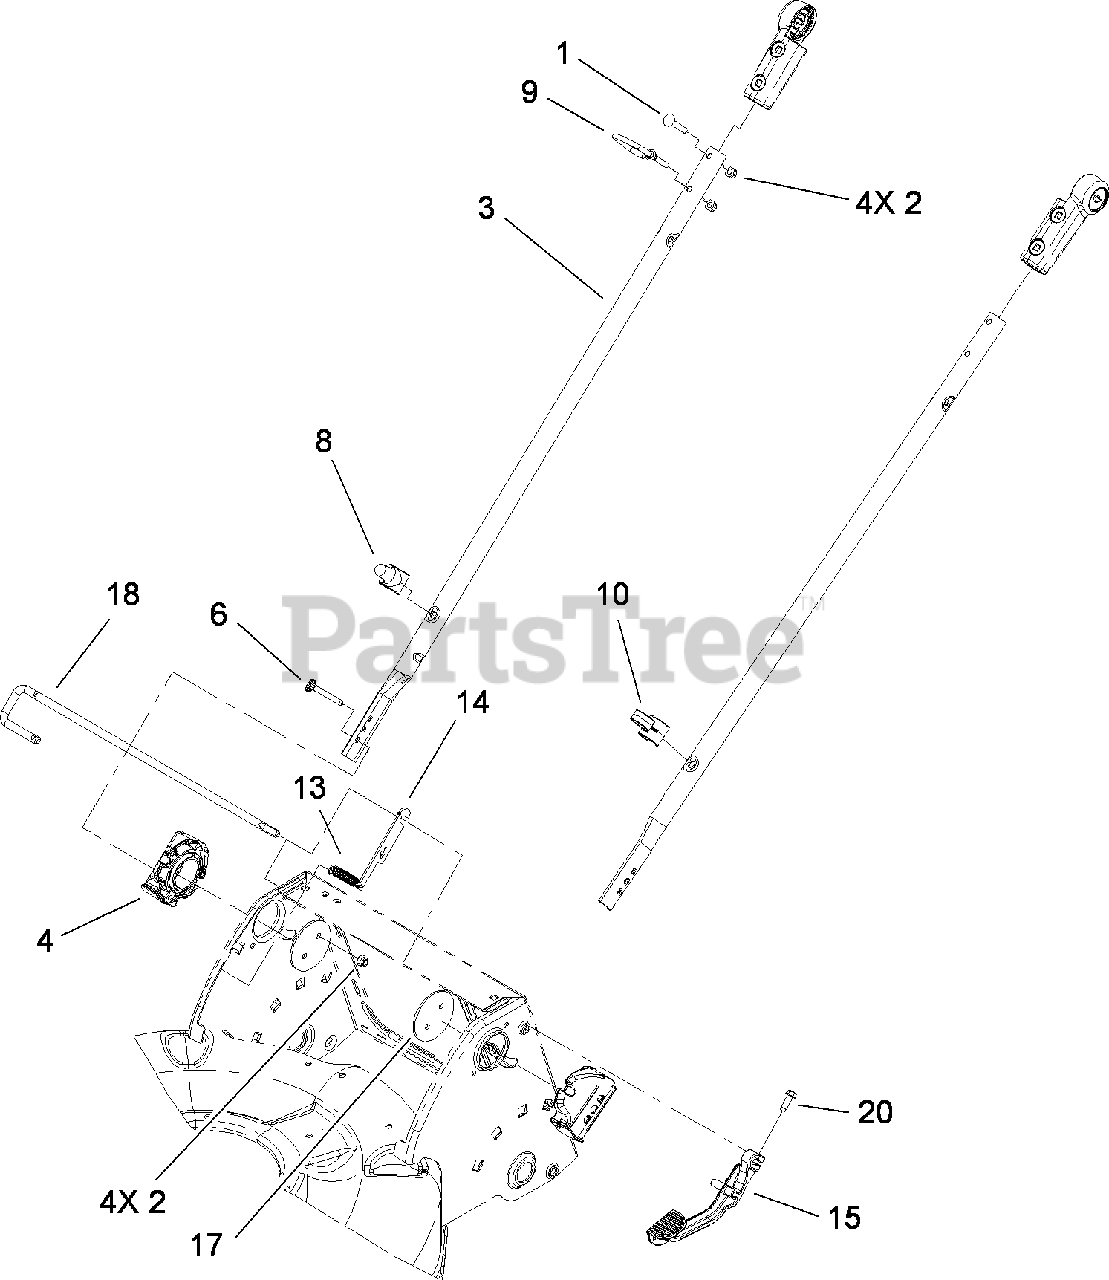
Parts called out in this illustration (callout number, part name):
1	SCREW-CARR
2	NUT-LOCK, NI
4	HANDLE-MOUNT, LOWER
8	GUIDE-ROPE, LOWER
9	GUIDE-ROPE, UPPER
10	Guide-Cable
13	SPRING-EXTENSION
14	PLATE-RELEASE ROD
15	LEVER-RELEASE
18	ROD-HANDLE RELEASE
20	SCREW-HWHTF
